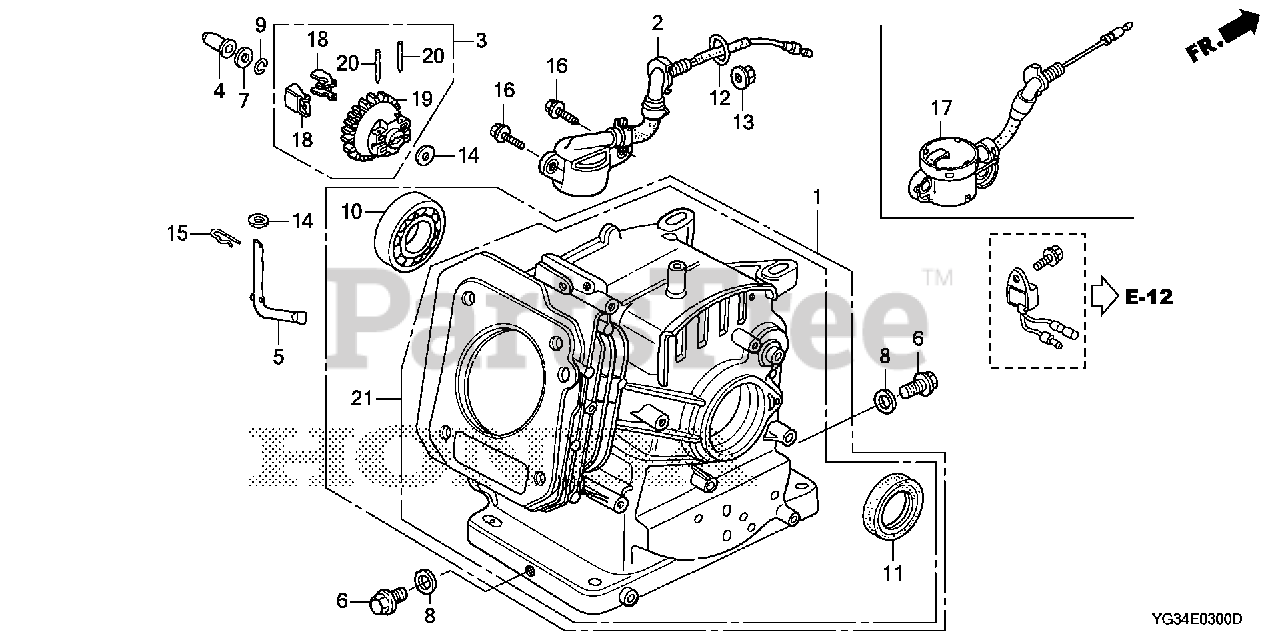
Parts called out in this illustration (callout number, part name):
1	CYLINDER ASSY. (OIL ALERT)
3	GOVERNOR ASSY.
4	SLIDER, GOVERNOR
5	SHAFT, GOVERNOR ARM
6	BOLT, DRAIN PLUG
8	WASHER, DRAIN PLUG (10.2MM)
9	CLIP, GOVERNOR HOLDER
10	BEARING, RADIAL BALL (6205)
10	BEARING, RADIAL BALL (6205) (NSK)
11	OIL SEAL (25X41X6)
11	OIL SEAL (25X41X6) (ARAI) (NOT AVAILABLE)
12	O-RING (14MM) (ARAI) Use up to Engine SN 2949254.
12	O-RING (14MM) (NOK)
13	NUT, FLANGE (10MM)
14	WASHER, PLAIN (6MM)
15	PIN, LOCK (8MM)
16	BOLT, FLANGE (6X12) Use up to Engine SN 1543277.
17	SWITCH ASSY., OIL LEVEL
18	WEIGHT, GOVERNOR
19	HOLDER, GOVERNOR WEIGHT
20	PIN, GOVERNOR WEIGHT
